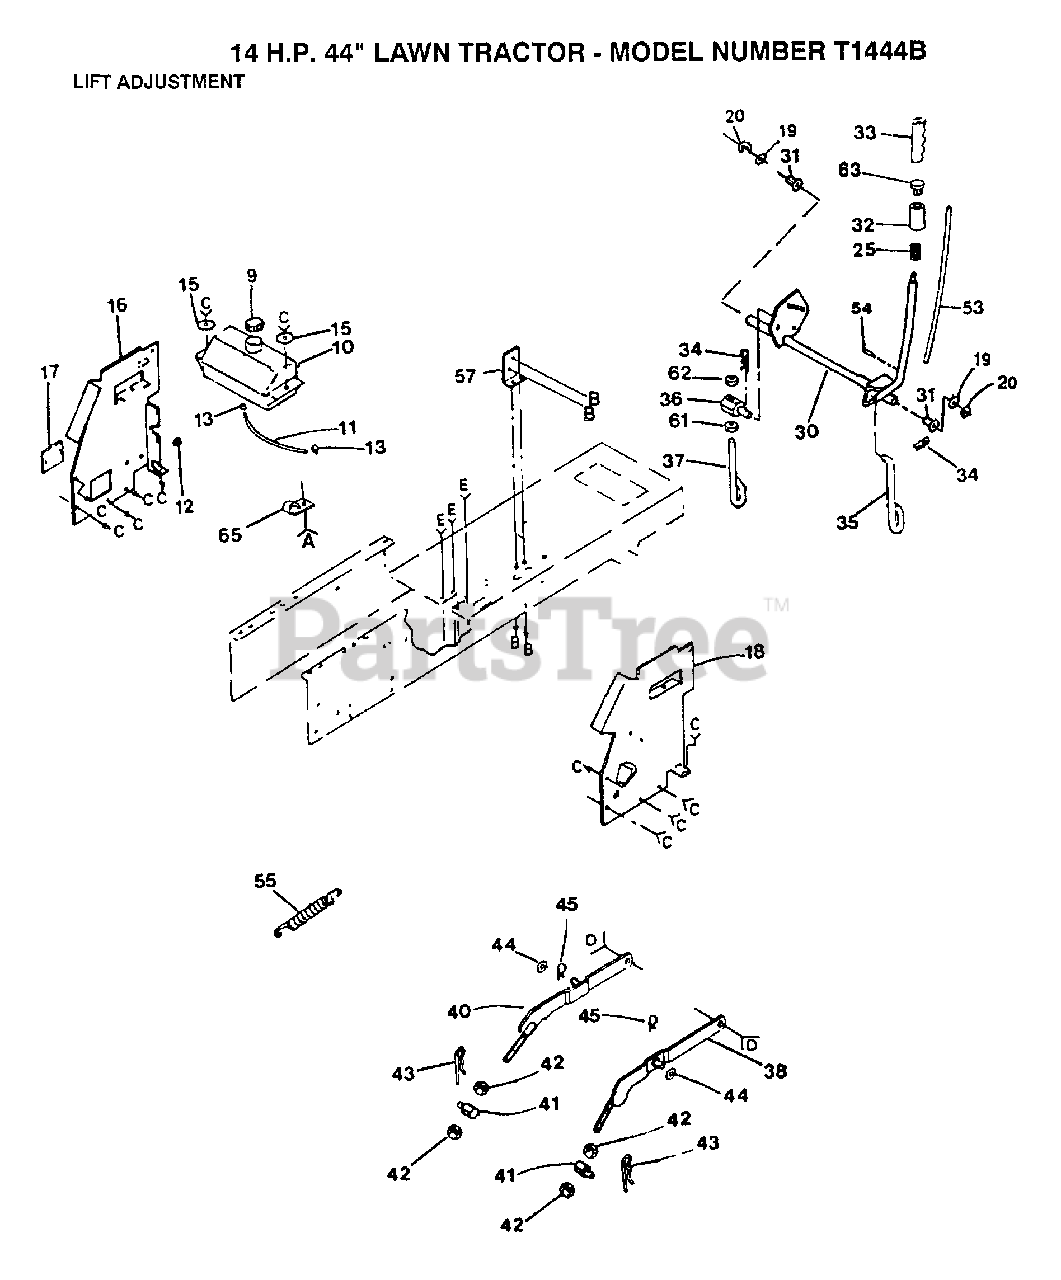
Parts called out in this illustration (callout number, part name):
10	TANK.FUEL.LT.
11	FUEL LINE T
13	HOSE CLAMP
15	WASHER
16	PANEL DASH LH
17	COVER ACCESS
19	WASHER
31	NYLON BEARING
33	GRIP
35	LIFT LINK LT
37	PIVOT PIN T
38	RH SUSP ARM ASM
40	LH SUSP ARM ASM
42	NUT
43	SPRING H
45	SPRING.RETAINER
54	PIN-GROOVE LT
57	BRACKET LT
61	NUT
65	INSUL CLIP T
